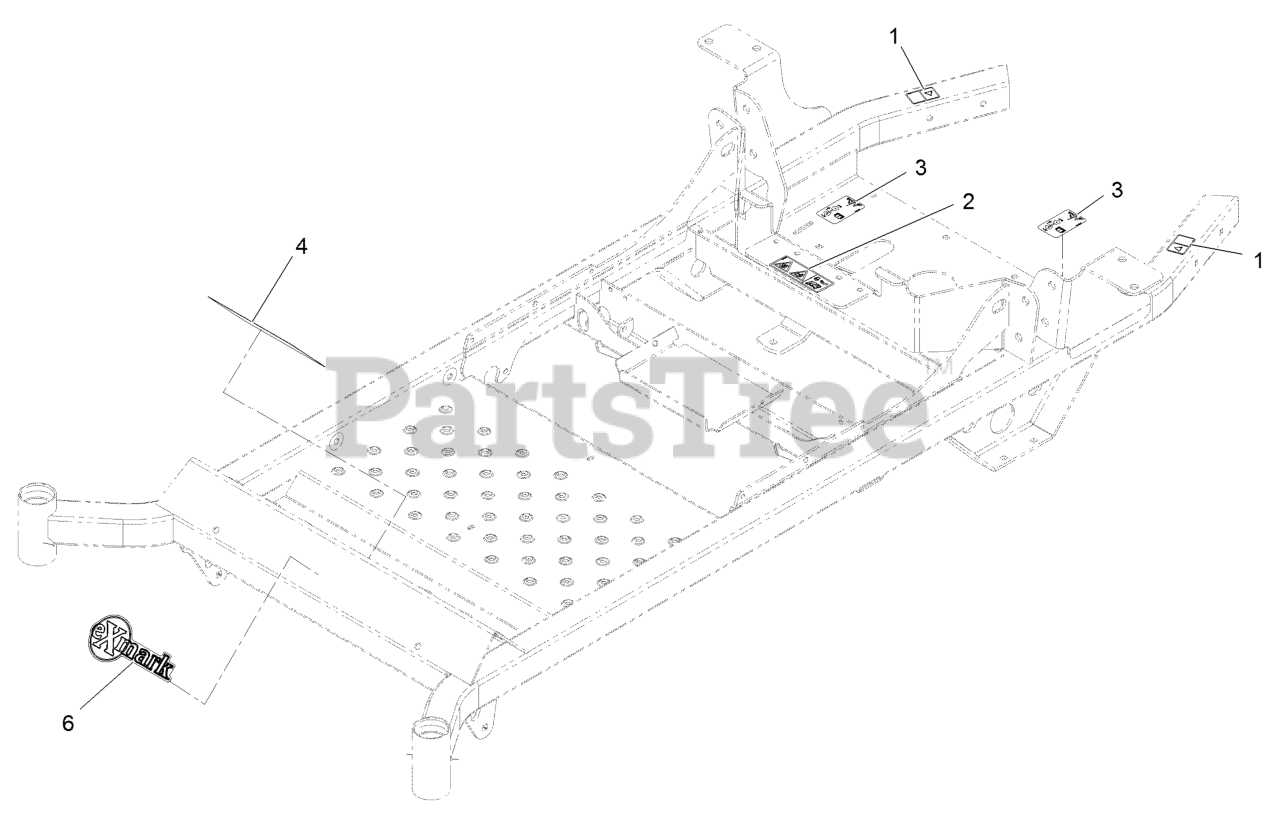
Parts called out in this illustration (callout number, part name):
1	DECAL-WARNING
2	DECAL-WARNING
3	DECAL-RELEASE, DRIVE
4	DECAL-DANGER
6	DECAL, EXMARK LOGO
